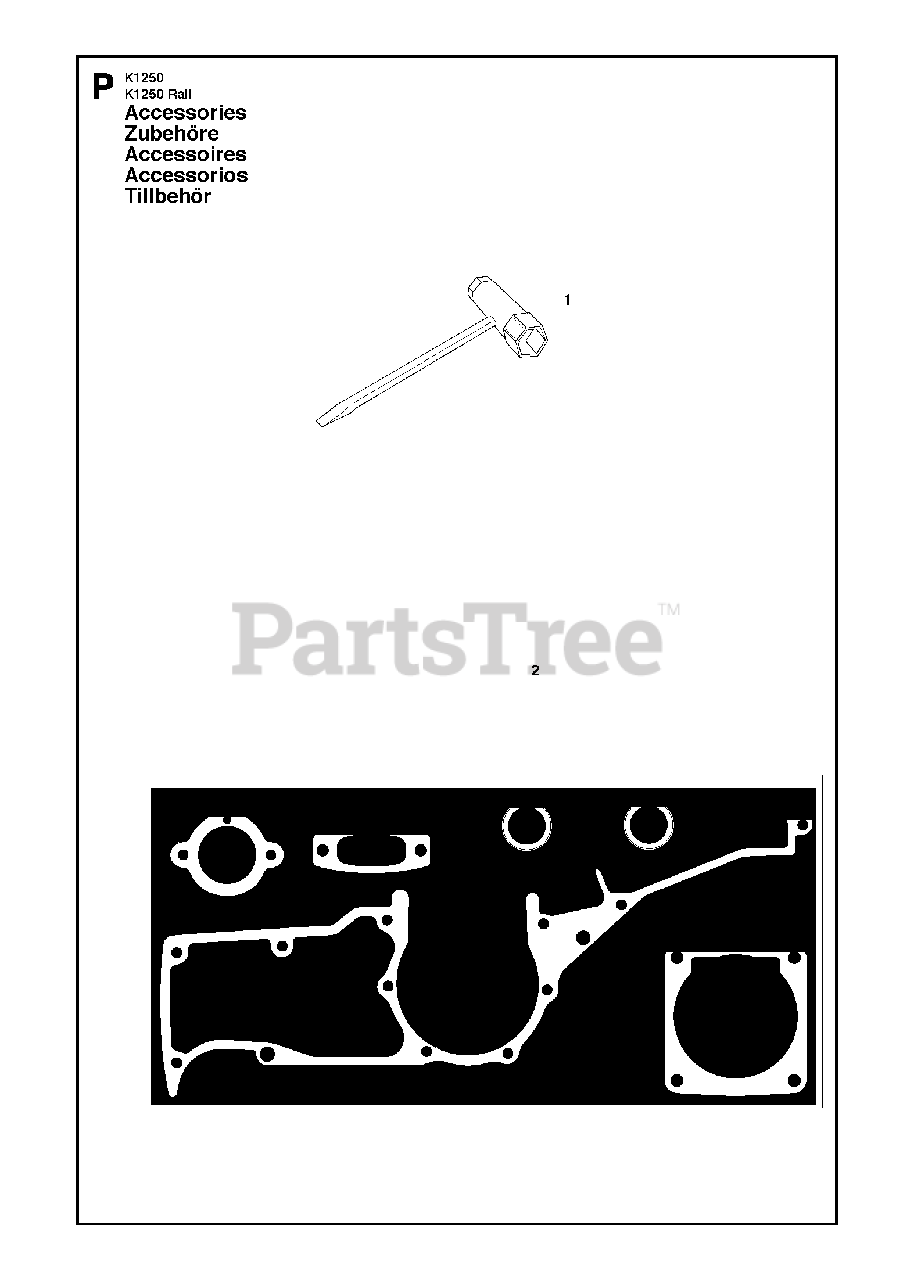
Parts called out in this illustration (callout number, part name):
1	COMBINATION WRENCH
3	GASKET
4	GASKET
5	SEALING RING
